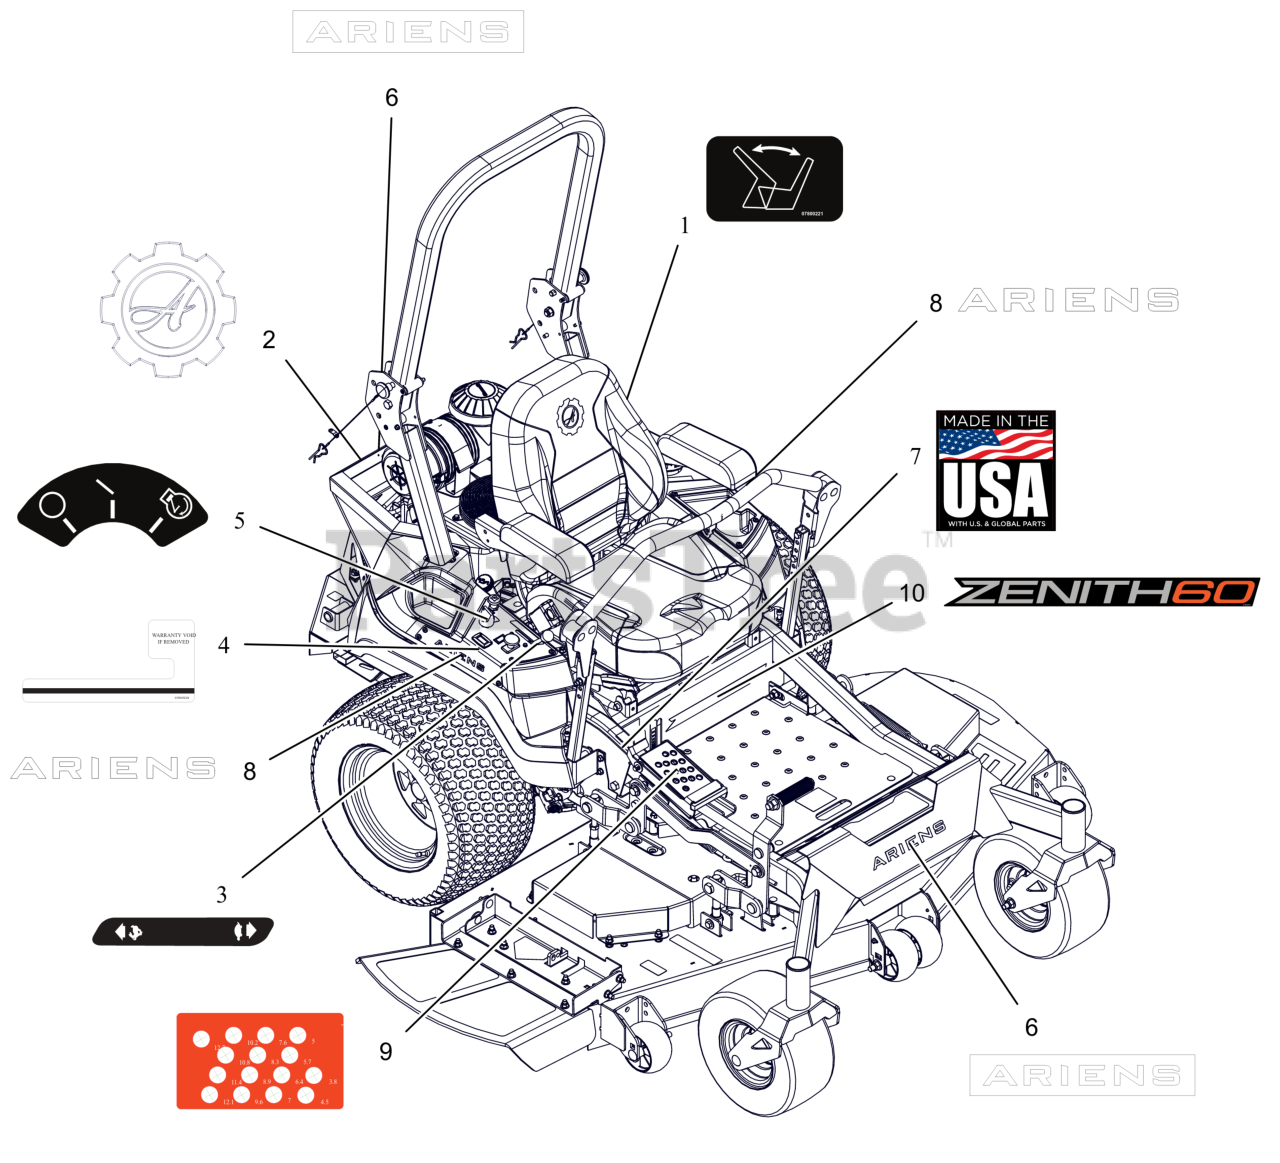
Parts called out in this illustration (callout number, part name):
1	DECAL - SEAT RELEASE
2	DECAL, ARIENS-GEAR BADGE -THK
3	DECAL, DASH DECAL
4	DECAL,HOURMETER - SECURITY
5	DECAL, KEYSWITCH
6	DECAL - ARIENS 9.625"
7	DECAL, MADE IN USA
8	DECAL, ARIENS (6.50")
9	DECAL, APEX HOC METRIC
10	DECAL, ZENITH 60
